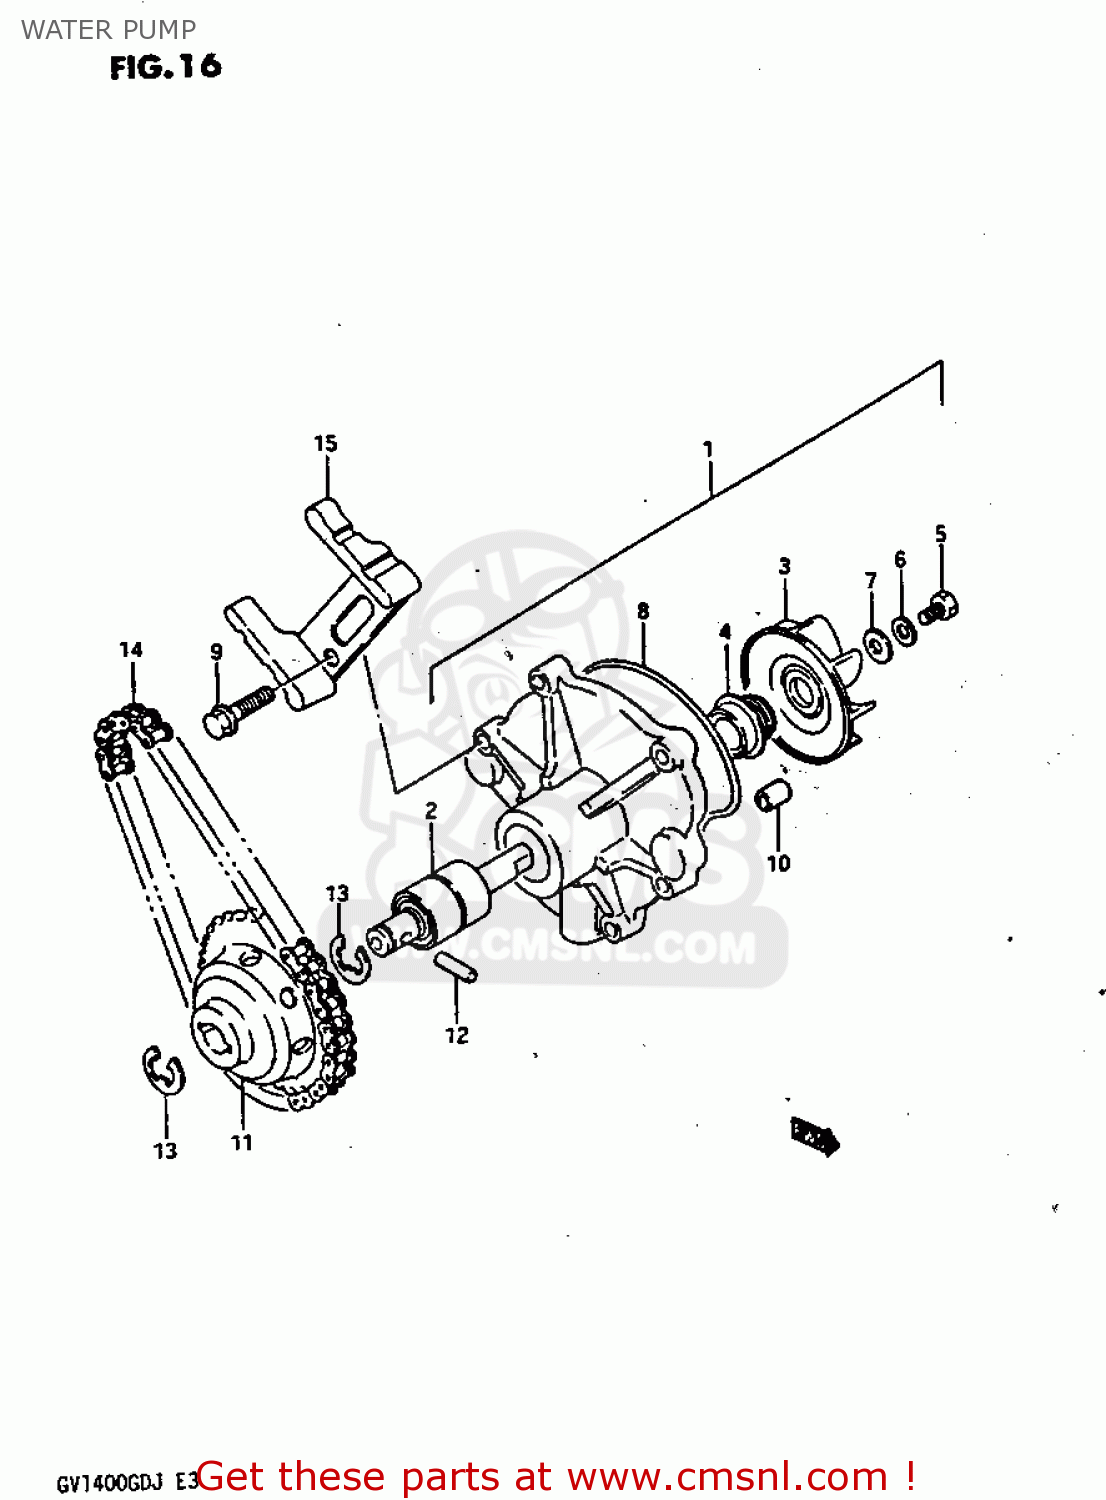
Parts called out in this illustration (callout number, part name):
1	PUMP ASSY,WATER
2	SHAFT,WATER PUMP
3	IMPELLER
4	SEAL,MECHANICAL
5	BOLT(6X13)
6	WASHER
7	GASKET(6X15X2.2) (NAS)
8	O RING,WATER PUMP CASE
9	BOLT 6X25
10	PIN
11	SPROCKET COMP,WATER PUMP
12	PIN(5.1X18.8)
13	E RING
14	CHAIN,WATER PUMP DRIVE
15	GUIDE,DRIVE CHAIN
